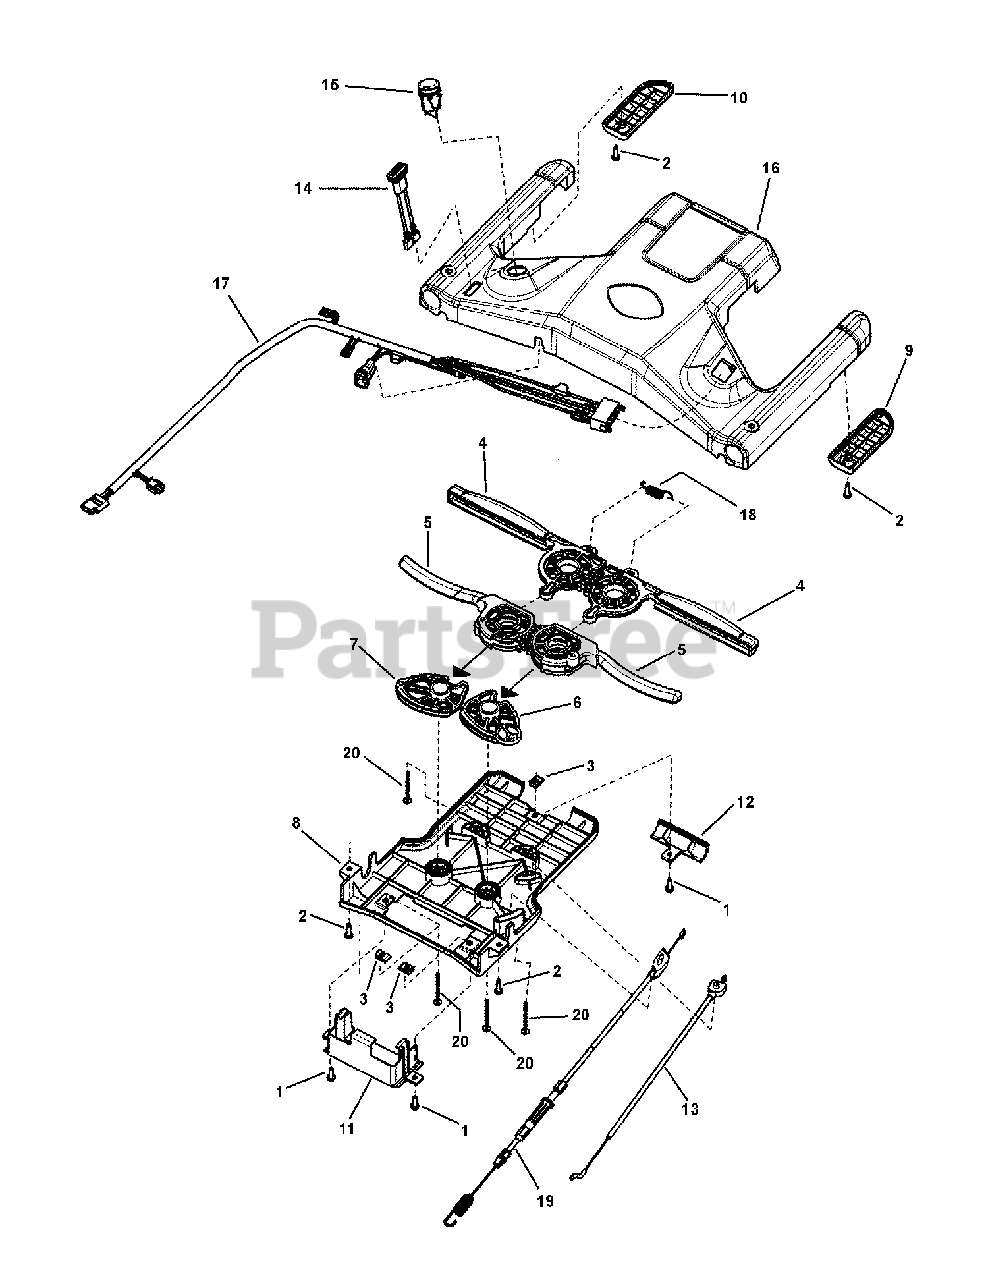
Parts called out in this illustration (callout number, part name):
1	SCREW, #10-24 x 5/8" Hex Washer Self-Tap, GR 5 BZ
2	SCREW, #10-16 x 3/4" Pan Head Self-Tap Combo, BZ
3	NUT, #10-24 Speed Retainer w/extrusion
4	LEVER, Drive Control
5	LEVER, OPC, Control
6	CAM, Drive, LH
7	CAM, Drive, RH
8	CONTROL PANEL, Bottom, MY Mower
9	PANEL, Bottom Control, WBM, RH
10	PANEL, Bottom Control, WBM, LH
11	ACCESS DOOR, Battery Control Panel, WBM
12	PANEL, Access, Maintenance Reminder
13	CABLE, OPC, NXT
14	HOUSING, Bridge Disconnect
15	SWITCH, Push Button Start
16	CONTROL PANEL, Top
17	HARNESS, Electric Start, NXT, w/E-HOC
18	SPRING, Tension, Drive Control
19	CABLE, Control, NXT
20	SCREW, #10-16 x 2" Hi-Lo Cross Pan Head
